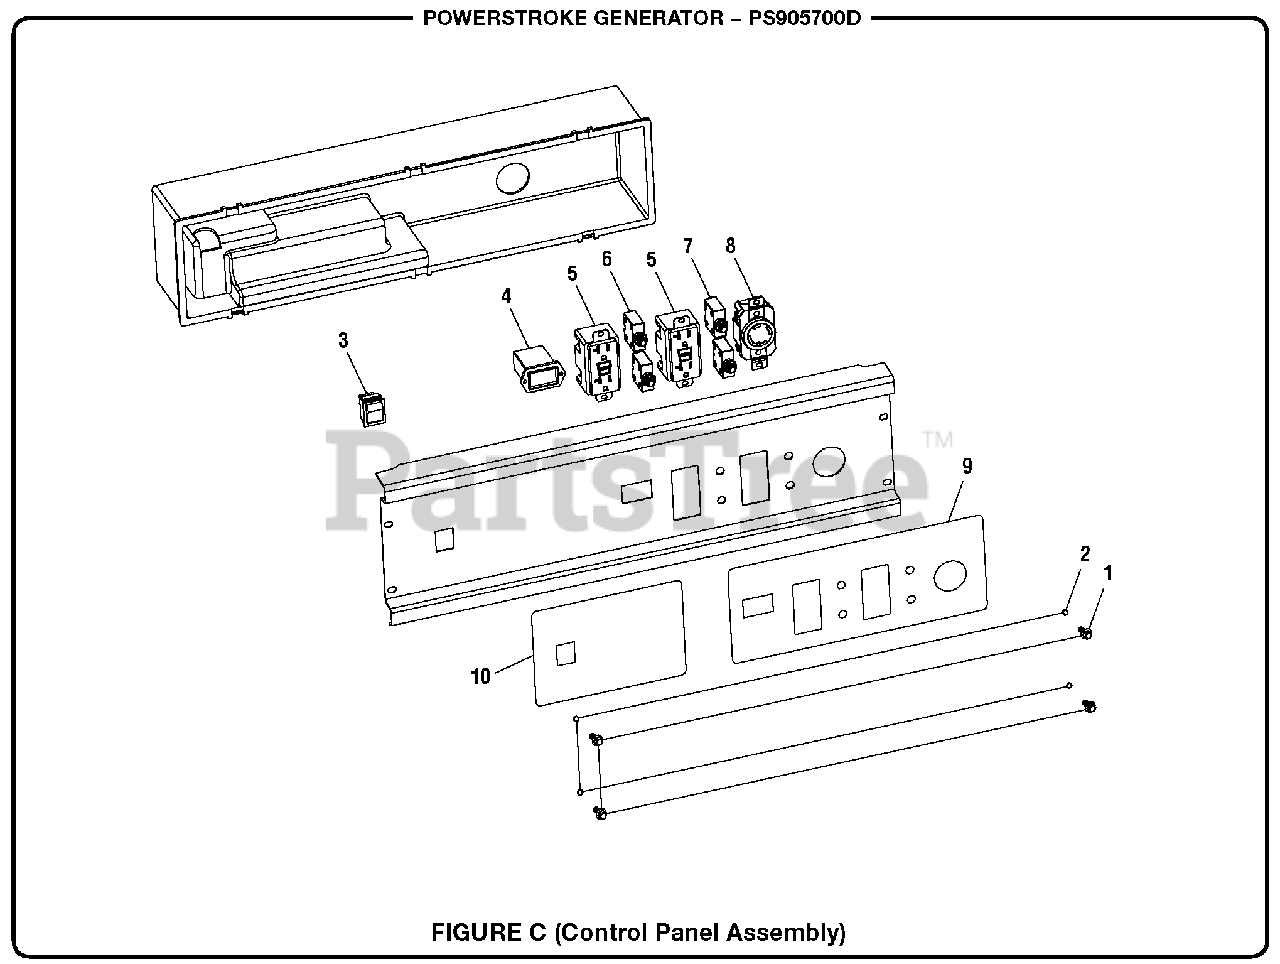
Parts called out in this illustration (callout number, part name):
3	Switch Assembly
4	Hour Meter
5	120 Volt Duplex Receptacle
6	Circuit Breaker (20 Amp)
7	Circuit Breaker (25 Amp)
8	220 V Twist Lock Receptacle
9	Outlet Panel Label
10	Performance Label
